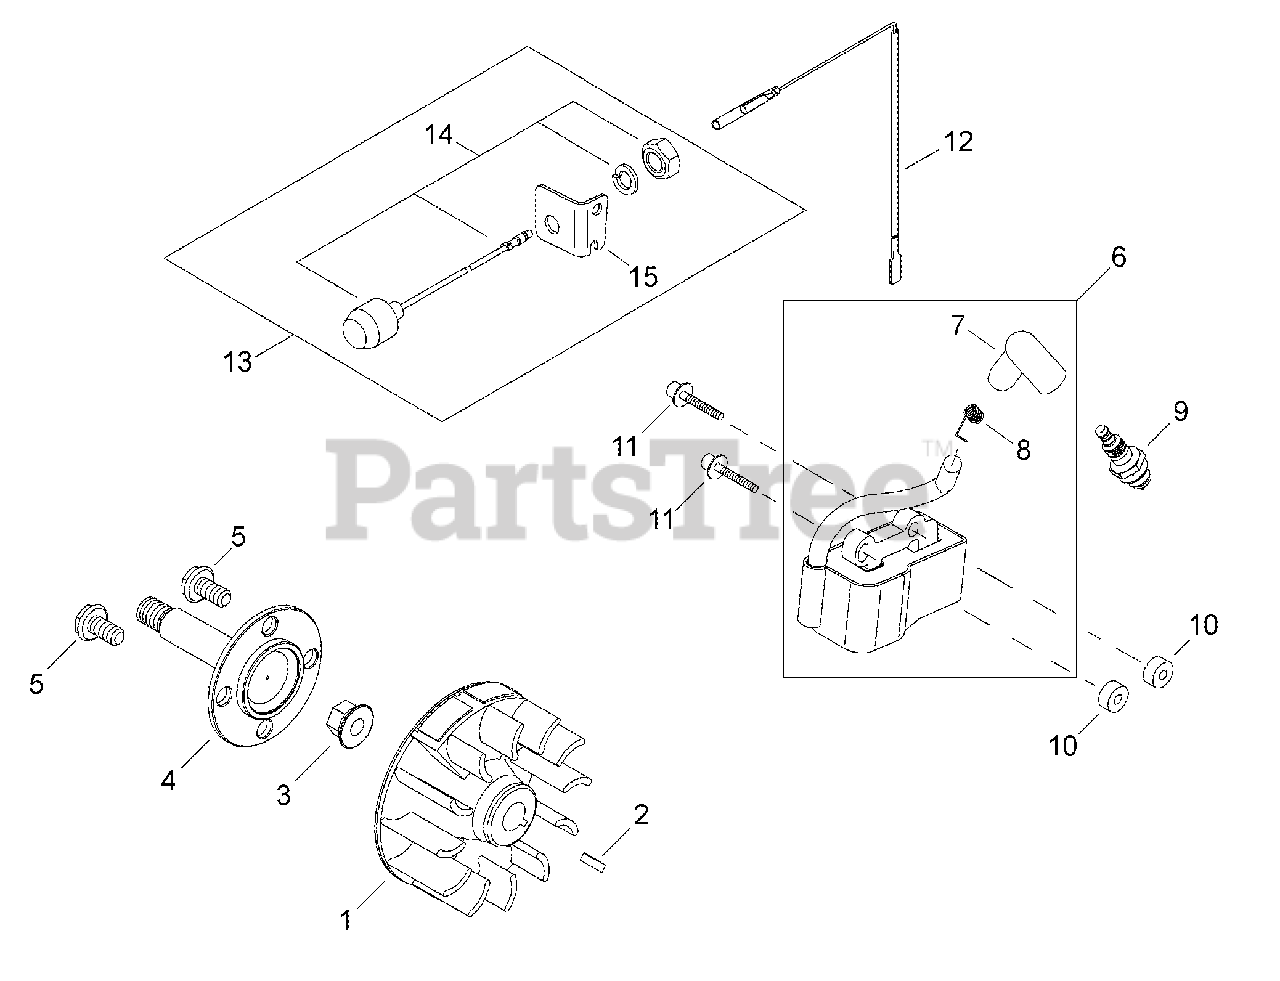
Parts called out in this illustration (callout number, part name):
1	FLYWHEEL Ø95
2	KEY, WOODRUFF 3×10
3	NUT M8
4	SHAFT, PUMP
5	BOLT, FLANGE M8×16
6	COIL ASSY, IGNITION
7	CAP, SPARK PLUG
8	TERMINAL, SPARK PLUG
9	SPARK PLUG - CMR5H
10	INSULATOR 4.2×11×6
11	BOLT M4×26
12	LEAD - IGNITION L= 220 MM
13	SWITCH ASSY, STOP W/BRACKET
14	SWITCH ASSY, STOP
15	BRACKET
